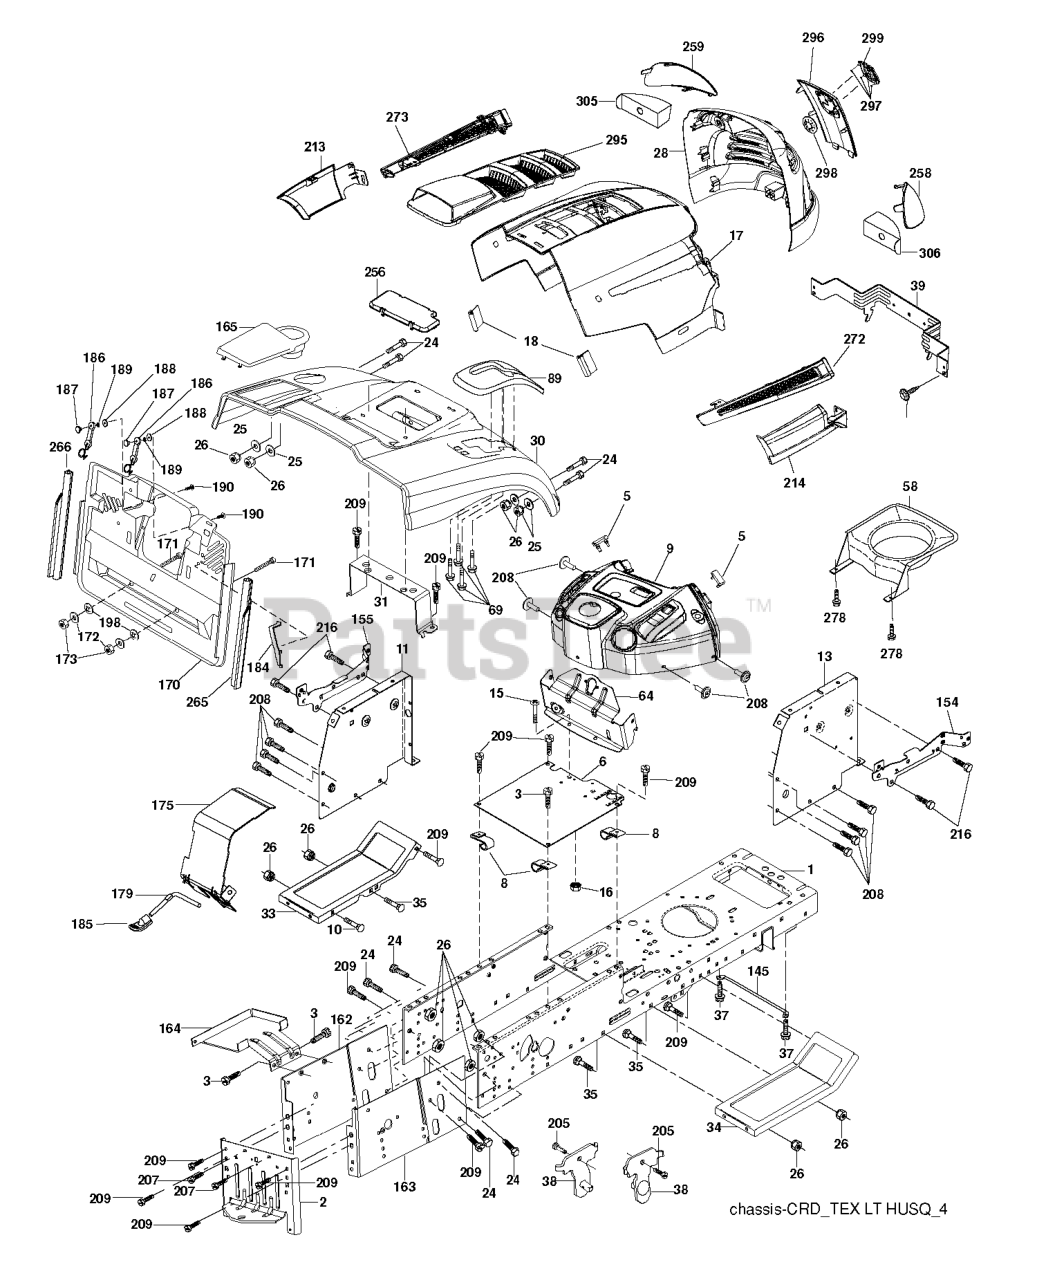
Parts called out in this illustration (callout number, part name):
2	DRAWBAR
3	SCREW 3/8-16X3/4
5	BUMPER DASH
6	PLATE
8	CLIP,INSULATOR
10	BOLT D
11	PANEL.DASH.LH.LTX
13	PANEL ASM, DASH RH
15	Screw, Machine, Truss Head 5/16-18 UNC x 3/4
16	NUT
17	HOOD
18	BUMPER.HOOD.TEX.HUSQVARNA
25	WASHER
26	NUT
28	RP GRILLE/LENS ASM.
30	CONSOLE.CRD.AUTO.GRY
31	BRACKET SUPPORT FENDER
33	FOOTREST PNT LH
34	FOOTREST PNT RH
37	Screw 5/16-18 x 1/2 Hex, Self Tapping 5/16-18 x 1/2
38	BRACKET ASM PIVOT MOWER REAR
39	BRACKET PIVOT
69	SCREW.HI-LO.CONSOLE
89	CONSOLE.CRD.AUTO.GREY.2005
145	ROD.PIVOT.HOOD
162	BRACKET
163	BRACKET EXTEN CHASSIS RH CRD
165	RP.COVER.BATTERY.CRD.GREY
172	WASHER
175	DOOR TRAP
179	ROD PIVOT FBI
184	BRACKET.ACTUATOR.BAGGER.SRD
186	LATCH ASSY
187	WELDNUT
189	LOCKWASHER #10
190	SCREW
207	SCREW, 5/16-18 X 1/2
208	SCREW 3/8-16X1/2
209	SCREW, 3/8-16X3/4
213	SKIRT SIDE LH
214	SKIRT SIDE RH
216	SCREW HEXWSHR 1/4-20X3/4
256	COVER FENDER CRD
258	LENS.HUSQVARNA LT.RH
259	LENS.HUSQVARNA LT.LH
265	SEALING
266	SEALING
272	VENT SIDE HOOD RH
273	VENT SIDE HOOD LH
278	SCREW.#10 X 0.750.BOS
295	VENT TOP HOOD
296	TRIM
297	CLIP.RETAINER.TINNER.
298	NUT PUSH M
299	RP LOGO
305	INSERT REFLECTIVE
306	INSERT.REFLECTIVE.RH.
